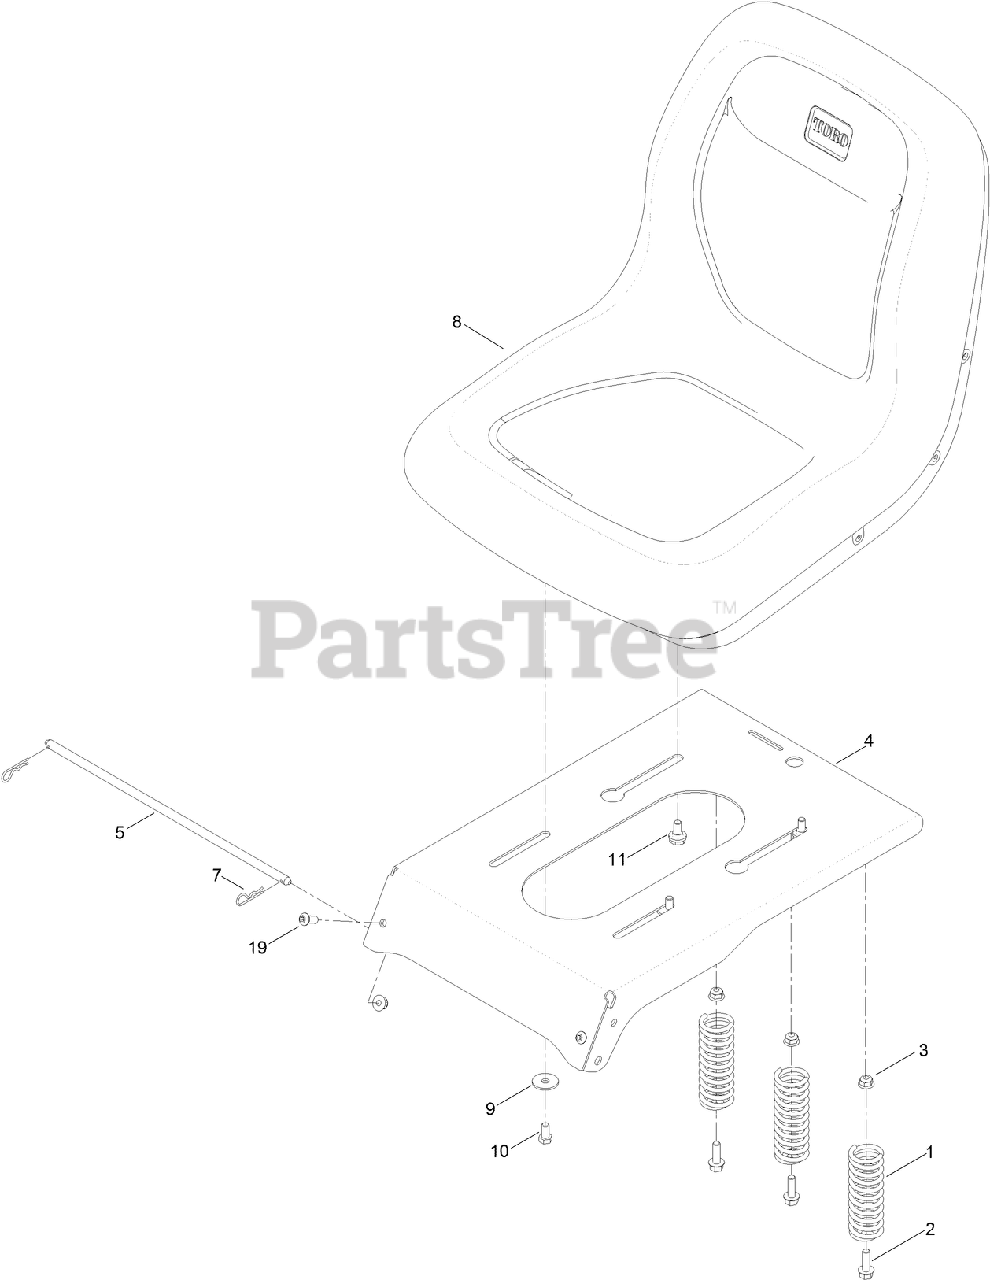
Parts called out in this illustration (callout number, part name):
1	SPRING-COMPRESSION
2	SCREW-HHF
3	NUT-HF, NI
4	PAN-SEAT
5	ROD-PIVOT, NARROW
7	PIN-COTTER
8	SEAT-18 INCH
9	WASHER-PIVOT
10	SCREW-HH
11	BOLT-SHOULDER,HFH
19	SCREW-HSBH
